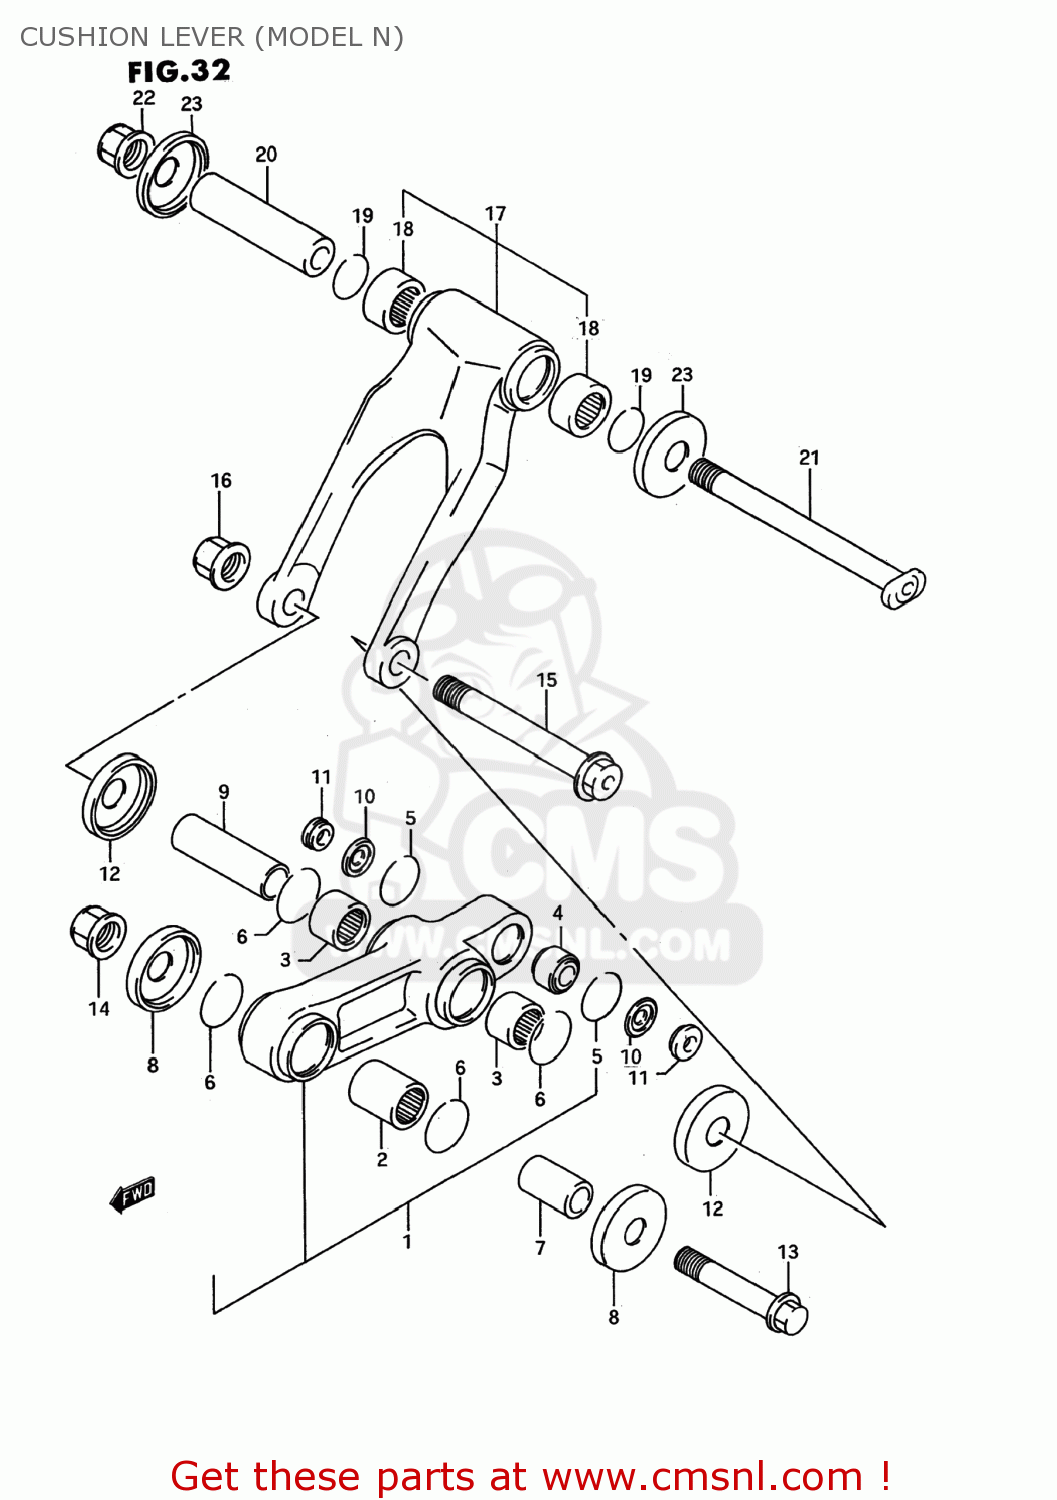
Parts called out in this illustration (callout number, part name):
1	LEVER SET,REAR CUSHION
2	BEARING(20X27X25)
3	BEARING(21X27X20)
4	BEARING,RR CUSHION LEVER RR
5	RING,BEARING STOPPER
6	CIRCLIP
7	SPACER,RR CUSHION LEVER FR
8	SEAL,REAR CUSHION LEVER
9	SPACER,REAR CUSHION LEVER,C
10	SEAL,RR CUSHION LEVER RR DUST
11	SPACER,RR CUSHION LEVER RR
12	SEAL,REAR CUSHION LEVER
13	BOLT,RR CUSHION LEVER FR
14	NUT 12MM
15	BOLT,RR CUSHION LEVER CTR
16	NUT
17	LEVER SET,REAR CUSHION
18	BEARING(21X27X20)
19	CIRCLIP
20	SPACER,RR CUSHION ROD
21	BOLT,RR CUSHION ROD
22	NUT
23	SEAL,REAR CUSHION LEVER
